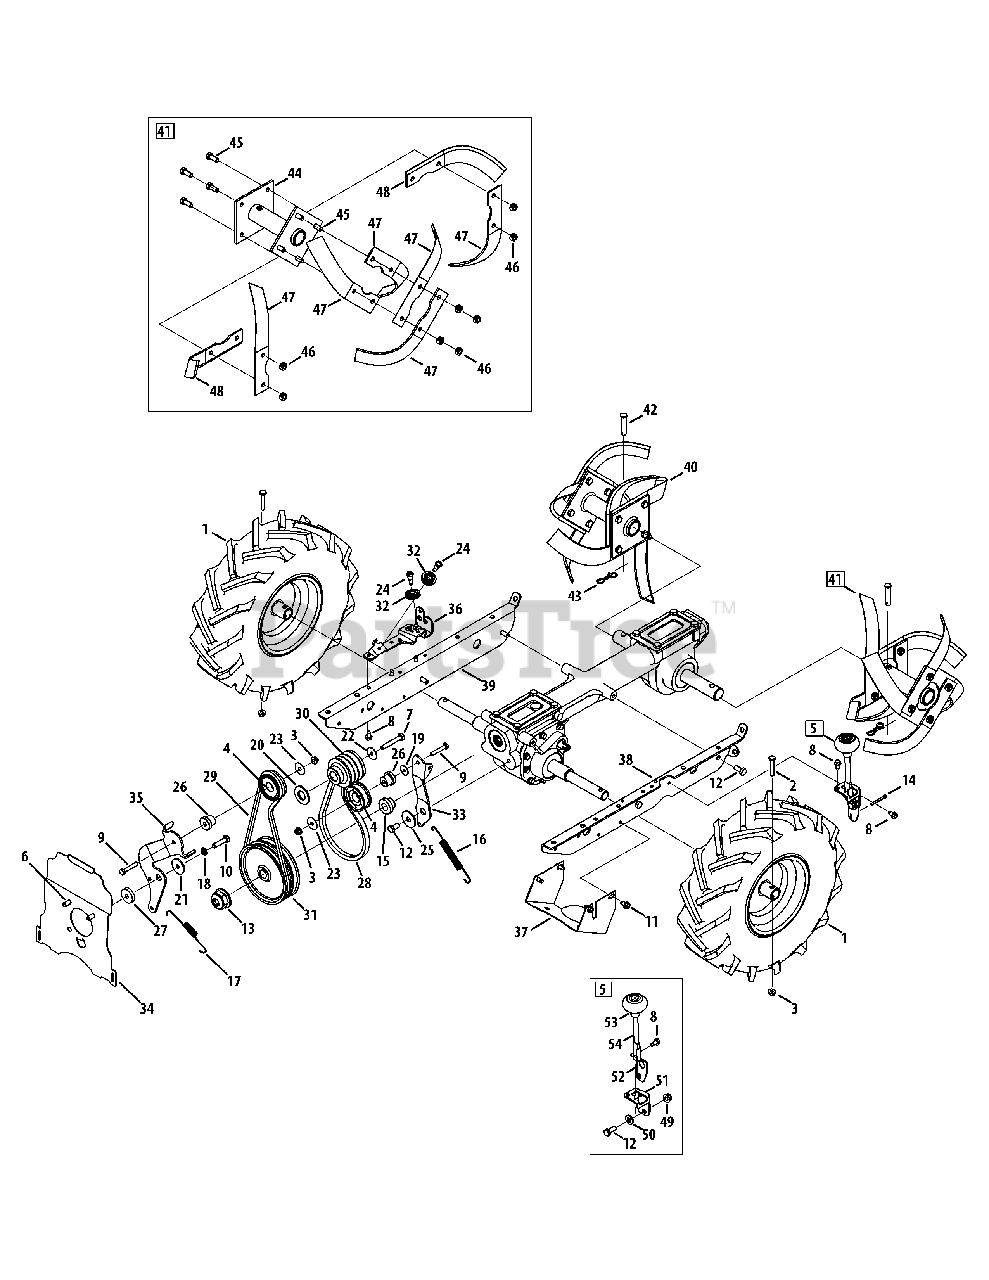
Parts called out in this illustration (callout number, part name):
1	Complete Wheel Assy., 14 x 4.5 x 6
1	Rim, 6.0 X 3.25
1	Tire, 14 x 4.5 x 6
2	Hex Head Screw, 1/4-20
3	Flange Lock Nut, 1/4-20
4	Idler Pulley Assembly
5	Pivot Bracket Assembly
6	Hex Head Screw, 5/16-24 x .625
7	Hex Head Screw, 3/8-24 x 2.25
8	Self-Tapping Screw, 1/4-20 x 1/2
9	Hex Head Screw, 1/4-20 x 1.50
10	Hex Head Screw, 5/16-18 x 1.25
11	Self Tapping Screw, 1/4-14 x .625
12	Hex Head Screw, 5/16-18 x .75, Patch
13	Nut, 9/16-18, Flange Lock
14	Cotter Pin, 5/32 x 1.25
15	Hub, 5/8 Spline
16	Extension Spring, .480 OD X 5.00 LG
17	Extension Spring
18	Lock Washer, 5/16
19	Washer, .28 x .74 x .063
20	Washer, Flat, .760 x 1.50 x .120
21	Flat Washer, .330 X 1.25 X .120
22	Bell Washer, .396 x 1.140 x .095
23	Flat Washer, .265 x 1.0 x .030
24	Shoulder Screw, .342 x .335 1/4-28
25	Pivot Idler Spacer
26	Shoulder Spacer, .260 x .785 x .538
27	Pivot Idler Spacer
28	V-Belt, 4L x 25.375 Long
29	V-Belt, 3L x 29.125 Long
30	Engine Pulley
31	Transmission Pulley
32	Cable Roller
33	Idler Bracket, Forward
35	Idler Bracket, Reverse
36	Pulley Bracket
37	Pulley Shield
38	Mounting Frame, LH
39	Mounting Frame, RH
40	Tine Assembly, RH
41	Tine Assembly, LH
42	Clevis Pin, .375 x 1.75
43	Cotter Pin, Bow Tie
44	Tine Holder Assembly
45	Hex Head Screw, 5/16-18 x .75
46	Nut, 5/16-18, Hexlock
47	Tine, RH
48	Tine, LH
49	Nylon Hex Lock Nut, 5/16-18
50	Pivot Spacer
51	Pivot Wheel Mounting Bracket
52	Pivot Wheel Bracket
